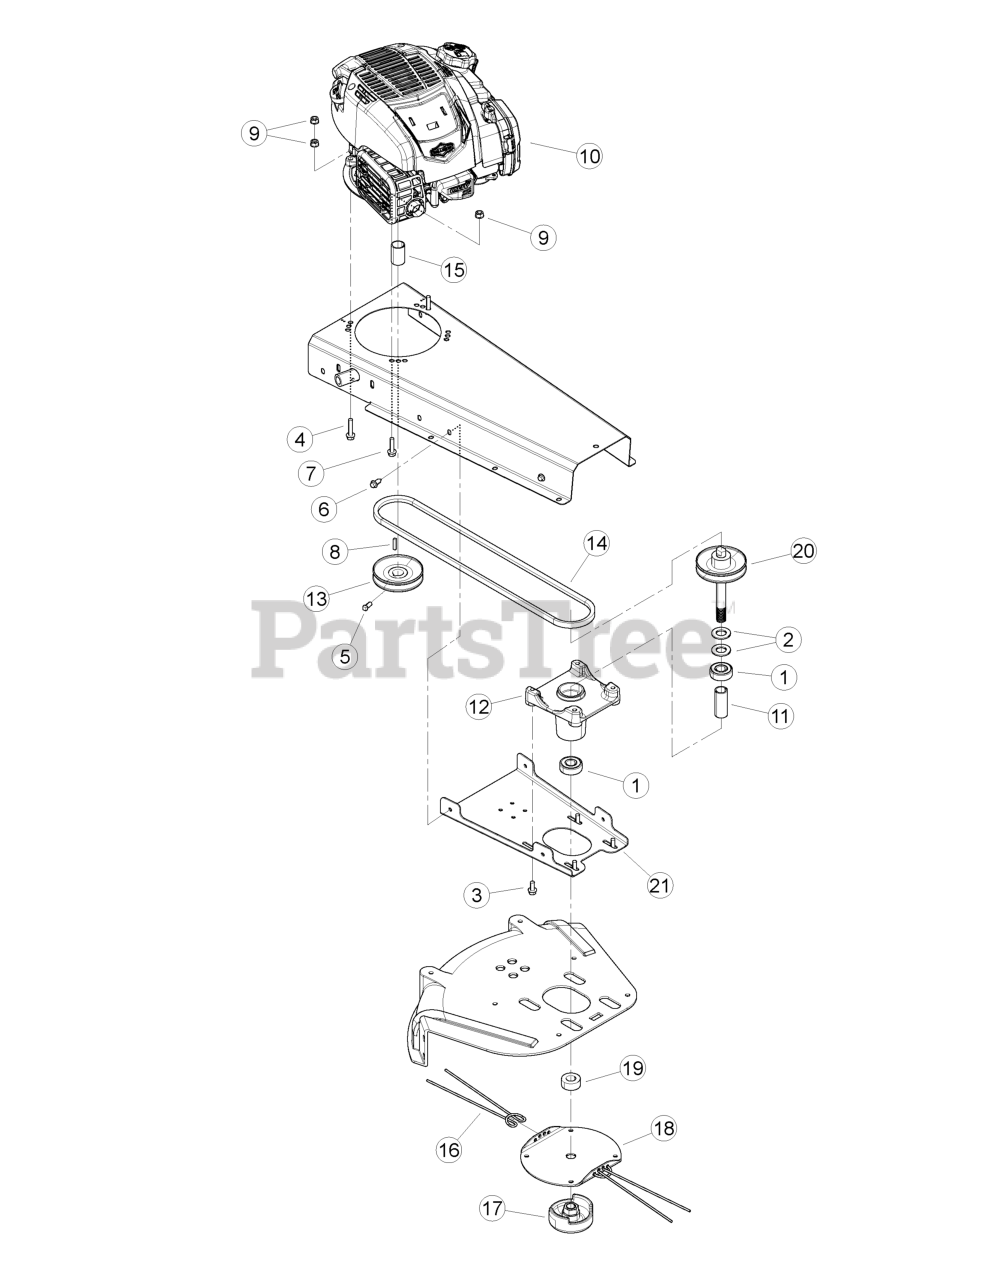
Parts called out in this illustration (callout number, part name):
1	BEARING, 3/4 BALL
2	WASHER, 3/4" SAE FLAT ZP
3	BOLT, 5/16 × 3/4 FLANGE NC
4	BOLT, 5/16 × 1-1/2 FLANGE NC
5	SCREW, 5/16-18 × 5/8 SQ HD SET
6	SCREW, 11/32-12 × 7/8 FLANGE T-AB
7	BOLT, 5/16 × 1-1/4 FLANGE NC
8	KEY, 3/16" × 1.00" LG SQUARE
9	NUT, 5/16-18 NYLOCK FLANGE
10	ENGINE, BRIGGS 163cc VERTICAL
11	SPACER, TRIMMER SPINDLE
12	CASTING, TRIMMER SPINDLE HUB
13	PULLEY, ENGINE 4.0 × .875 B GROOVE
14	BELT, AX48
15	SPACER, 1-1/16 OD × 14 GA × 1.630
16	STRING, 20" × .155 DIA. Cross-Fire®
17	MOWBALL, CAST TRIMMER PAINTED
18	DISK, TRIMMER HEAD
19	SPACER, TRIMMER HEAD
20	WELDMENT, SPINDLE HW MODELS
21	PLATE, SPINDLE CASTING MOUNT
